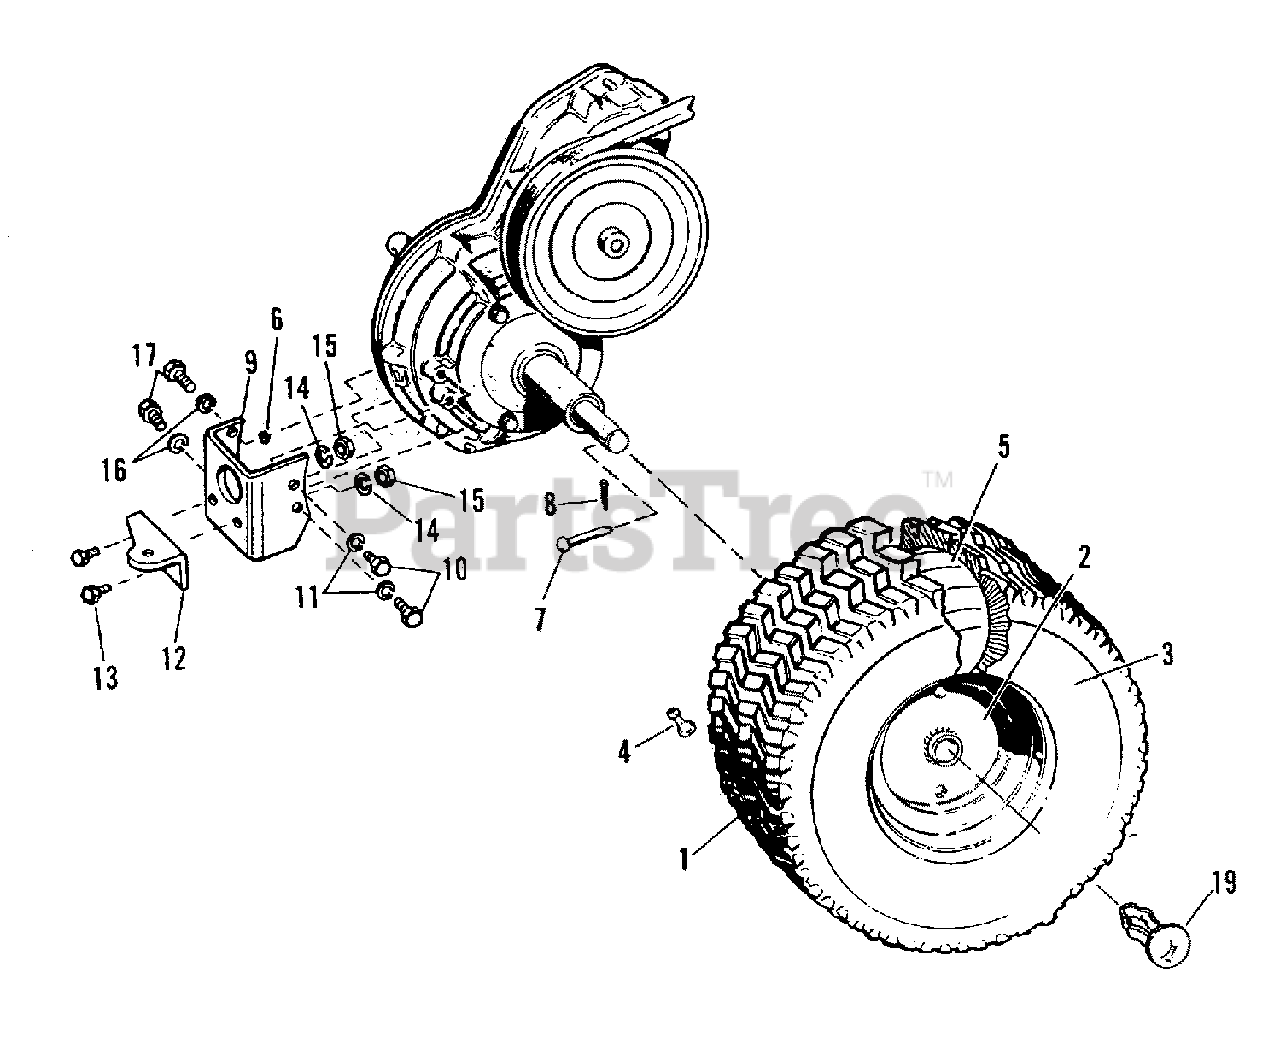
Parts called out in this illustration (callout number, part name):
1	WHEEL & TIRE ASSEMBLY, R.H.
2	WHEEL ASSEMBLY, R.H.
4	VALVE STEM & CAP
6	WASHER, Plain, 5/16"
7	PIN
8	PIN, Cotter, 1/8" x 3/4" ig.
9	BRACKET, Draw Bar
10	CAPSCREW, Hex, 3/8"-16 x 3/4" ig.
11	LOCKWASHER, 3/8"
12	CLIP, Draw Bar Hitch
13	CAPSCREW, 3/8"-16 x 1" Ig.
14	LOCKWASHER, 3/8"
15	NUT, Hex, Full, 3/8"-16
16	LOCKWASHER, 5/16"
17	CAPSCREW, 5/16"-18 x 1-1/4" Ig.
18	BUTTON, Plug, R.H.
19	BUTTON, Plug, L.H.
20	WHEEL & TIRE ASSEMBLY, L.H.
21	WHEEL ASSEMBLY, L.H.
